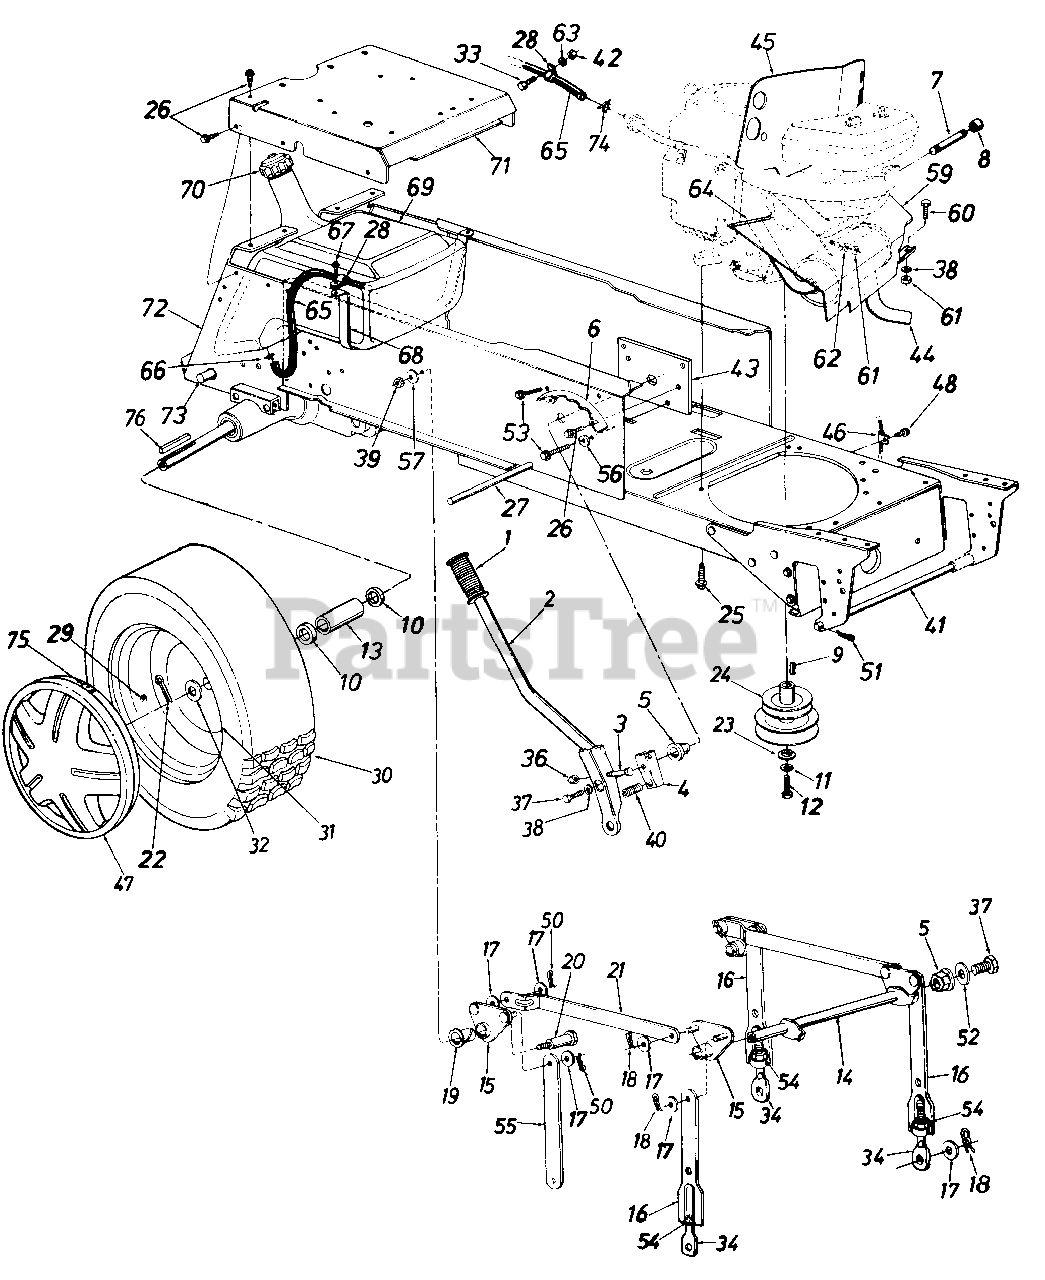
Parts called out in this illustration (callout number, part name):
1	Grip
2	Lift Handle Ass'y.
3	Hex Bolt 5/16-18 x 1.5" Lg.
4	Lift Shaft Drive
5	Plastic Hex Brg. 5/8n l.D.
8	Pipe Cap 3/8-18 Npt.
9	Sq. Key 1/4" x 1/4" x 1.50" Lg.
10	Fl-Wash. 1.03" I.D. x 1.62" O.D.
11	L-Wash. 7/16" I.D.
12	Hex Scr. 7/16-20 x 1.50" Lg.
13	Spacer 1.0" I.D. x 1.25" O.D.
14	Lift Shaft Ass'y.
15	Lift Pivot Brkt. Ass'y.
17	Fl-Wash. 1/2" I.D. x 1.00" O.D. x .090"
18	Hairpin Cotter
19	Nyliner 5/8" I.D. x .88" Lg.
20	Shld. Bolt 5/8" Dia. x 96n Lg. 3/8-16
23	Flat Wash. .44" I.D. x 1.25" O.D. x .17"
24	Two-Step Engine Pulley
25	Hex Wash. Hd. Scr. 3/8-16 x 1.25" Lg.
26	Hex Thd. Rolling Scr. 5/16-18 x.75" Lg.
27	Running Board Rod
29	Air Valve
33	Hex Bolt 1/4-20 x .62" Lg.
34	Eye Bolt Adj. Link 1/2-13 Thd.
36	Hex Cent. L-Nut 5/16-18 Thd.
37	Hex Scr. 5/16-24 x .62" Lg.
38	L-Wash. 5/16" I.D.
39	Hex Top L-Nut 3/8-16 Thd.
40	Compression Spring
41	Deck Connecting Rod
42	Hex Nut 1/4-20 Thd.
45	Heat Shield
46	Mounting Clamp
48	Hex Wash. Hd. TT-Tap Scr. 1/4-20 x ,5n Lg .
50	Cotter Pin .09 Dia. x l.On Lg.
51	Int. Cotter Pin
52	Flat Wash. ,34n l.D. x 1.12" O.D. x .125"
53	Hex Wash. Hd. AB-Tap Scr. 5/16-24 x ,5n Lg.
54	Hex Nut 1/2-13 Thd.
56	Fl-Wash. .344" I.D.
57	Bell-Wash. .4" l.D. x 1.13" O.D.
59	Front Heat Shield
60	Hex Bolt 5/16-18 x ,75n Lg.
61	Hex Nut 5/16-18 Thd.
62	L-Wash. 5/16" l.D.
63	L-Wash. 1/4" l.D.
64	Trim Strip 10n Lg.
65	Fuel Line 60n Lg.
67	Hex AB-Tap Scr. 1/4 x .62" Lg.
68	Fuel Tank Strap
69	Gas Tank
71	Seat Plate
75	Spring Clip
76	Sq. Key 1/4" x 3" Lg.
